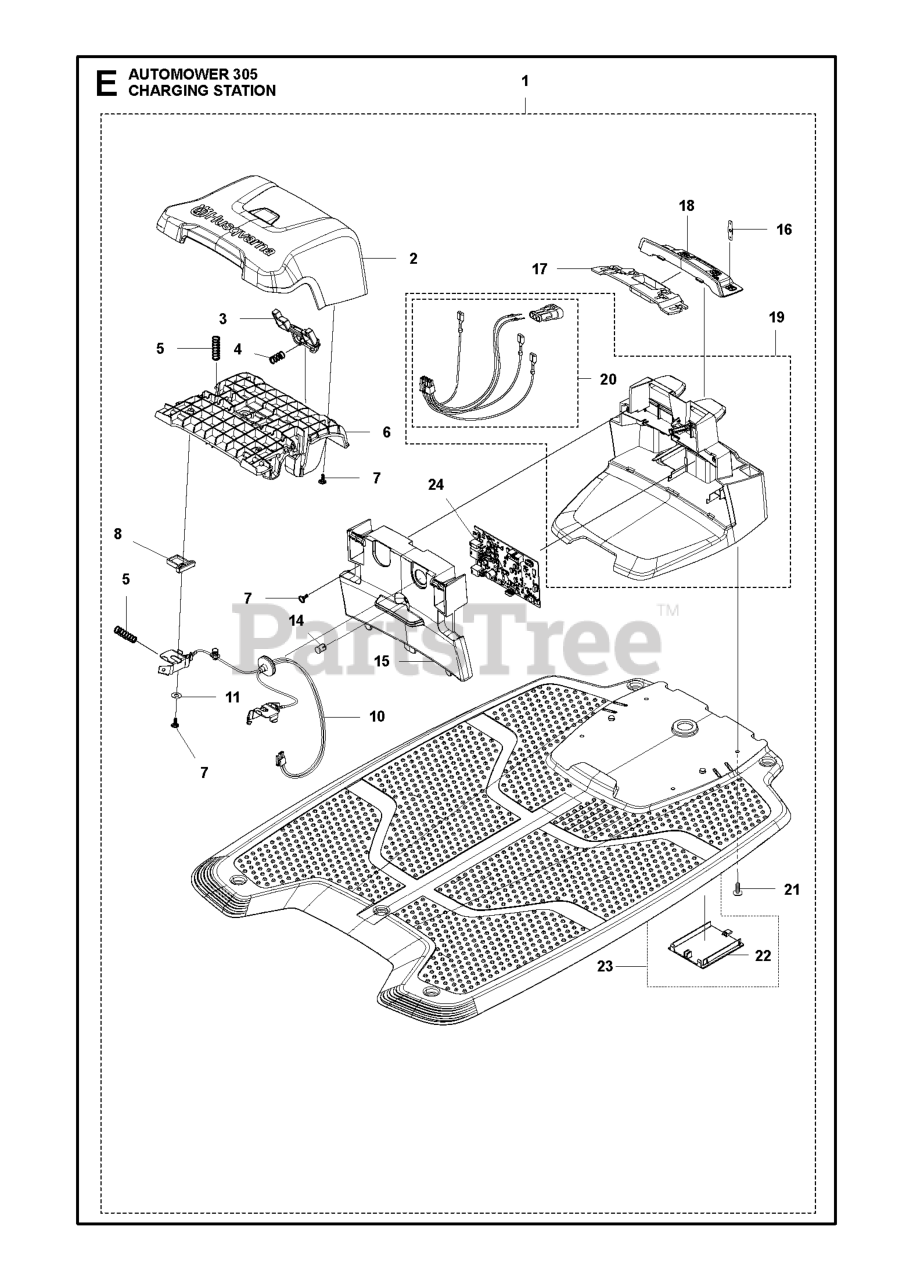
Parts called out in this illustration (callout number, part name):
1	Charging Station
2	CAP CHARGING STATION
3	BUTTON CHARGING STATION, RELEA
4	SPRING STOP BUTTON
5	SPRING SPRING CAP
6	FRAME CHARGING STATION
7	SCREW 14MM
10	CABLE ASSY CHARGING CONTACTS
14	LENS DIODE
15	LID CHARGING STATION
16	TERMINAL TERMINAL CHARGING STA
17	PAN CHARGING STATION 320, ONE
18	HOLDER CHARGING STATION
19	HOUSING ASSY CHARGING STATION
20	LOOM KIT GENERATOR BOARD
22	COVER CHARGING PLATE
23	CHARGING PLATE KIT
